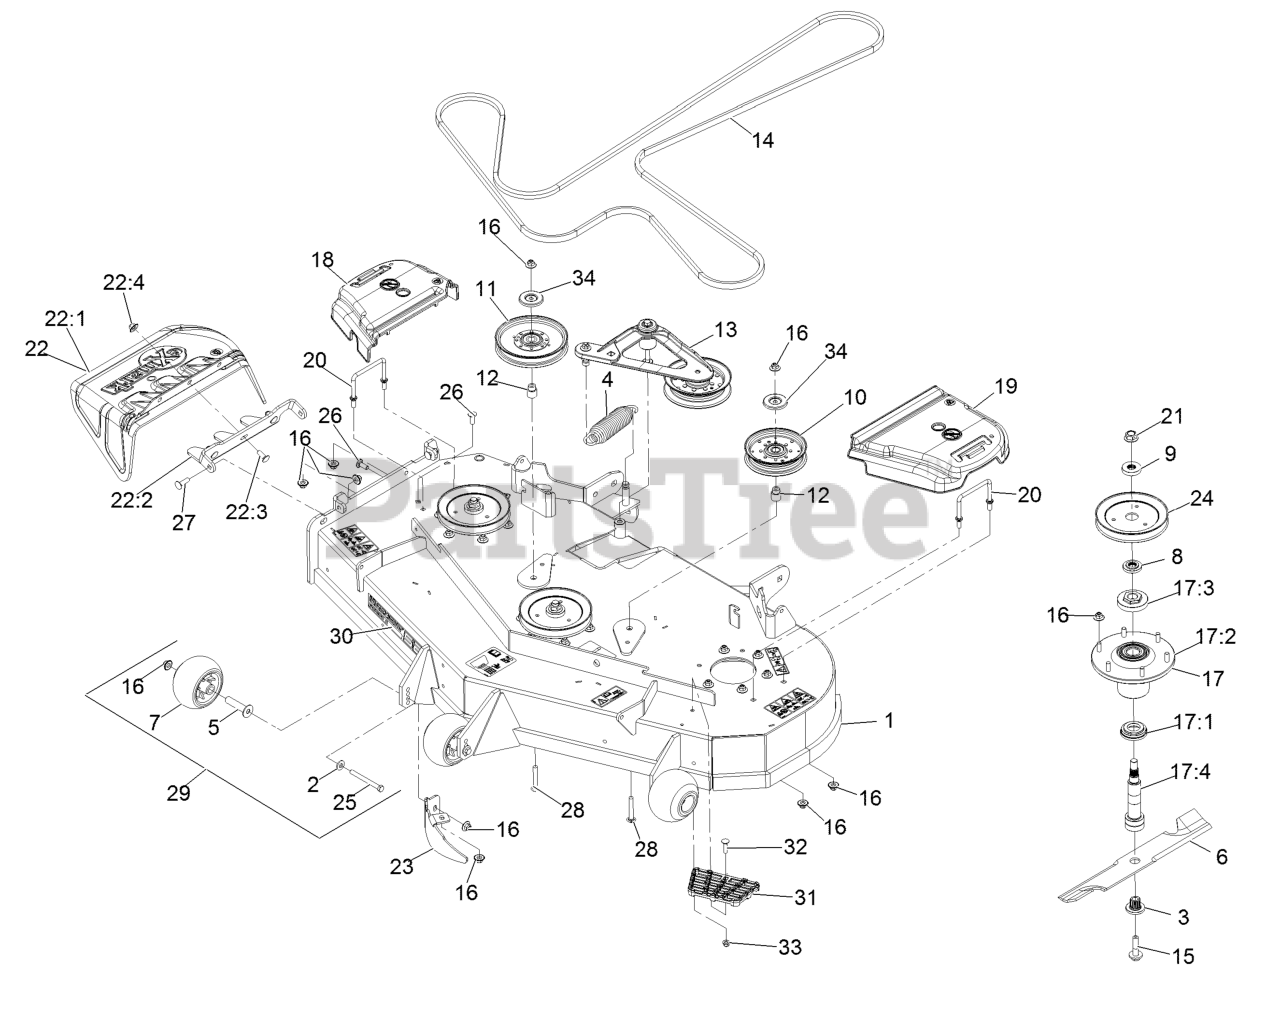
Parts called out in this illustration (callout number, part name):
1	ASM,Deck W/ Decals 52
2	Washer-Spring Disc 3/8
3	Bushing, Splined
4	Spring-Extension
5	Axle, Roller
6	Blade, Solid
6	Blade, Low Lift
6	Blade, Mulching
6	Blade-Notched
6	Blade-Extreme 2, 18.00"
7	Roller-Anti-Scalp
8	Spacer, Splined Stepped
9	Spacer, Splined
10	Idler-Pulley, Flat 5.00X0.95
11	Idler-Pulley, Flat 6.00X0.75
12	Bushing, Idler
13	Deck Idler ASM
14	Belt,V-B X 186.00"
15	Screw-Sems 1/2-20 X 2.19
16	Nut-Nyloc 3/8-16 Flg
17	ASM,Spindle Housing
17:1	Guard, Bottom
17:2	Asm, Cutter Housing
17:3	Nut, Spindle 7/8-14
17:4	Spindle,Double Spline
18	Cover-Belt, RH
19	Cover-Belt, LH
20	Wireform-Cover
21	Nut-Flange 5/8-18 Centerlock
22	ASM,Discharge Chute
22:1	Chute, Discharge
22:2	Bracket,Discharge Chute
22:3	Bolt-Carriage 3/8-16 X
22:4	Nut-Nyloc 3/8-16 Flg
23	Baffle-Dogleg, Lz-Vt52
24	Sheave,Blade Drive
25	Screw-HH 3/8-16 X 3 3/ GR 8
26	Bolt-Carriage 3/8-16 X 1
27	Bolt-Carriage 3/8-16 X 1 1/4
28	Bolt-Carriage 3/8-16 X 2 1/2
29	Kit, Anti-Scalp Roller
30	Decal, 526
31	Step-Deck
32	Bolt-Carriage 5/16-18 X 1 1/4
33	Nut-Nyloc 5/16-18 Flg
34	Shield-Dust
